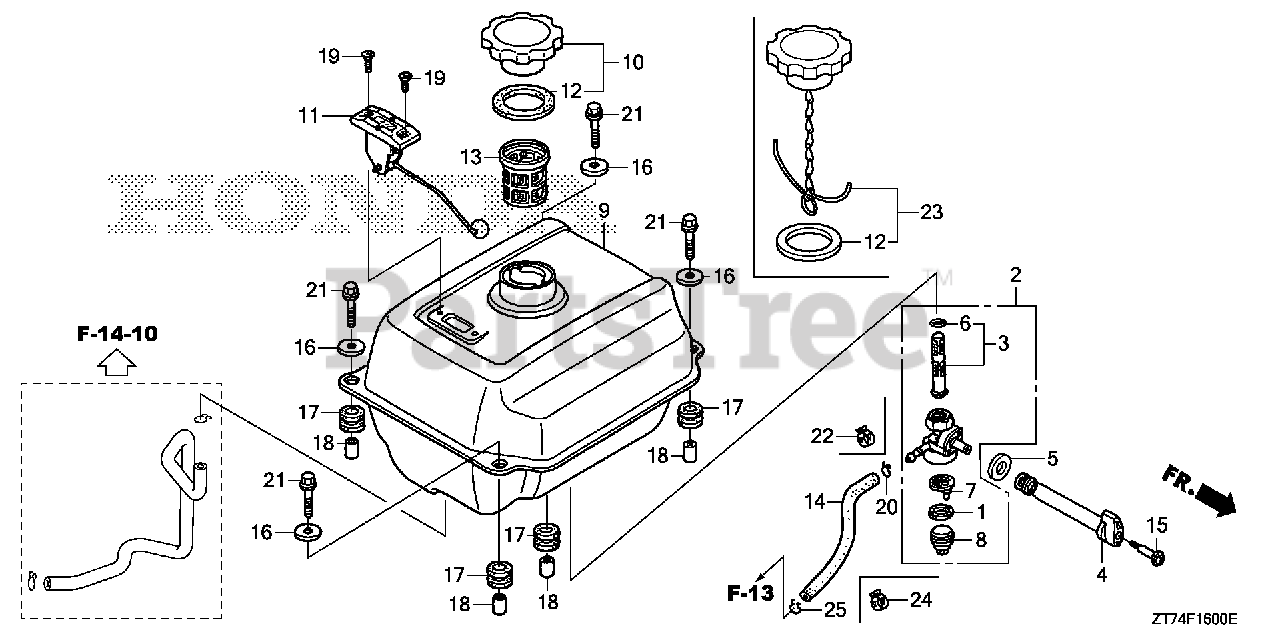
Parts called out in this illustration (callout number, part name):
1	GASKET, FUEL STRAINER CUP
2	PETCOCK ASSY.
3	SCREEN SET, FUEL STRAINER
4	LEVER, PETCOCK
5	SEAL, PETCOCK LEVER
6	O-RING (9.0X1.3)
7	FILTER, CUP
8	CUP, FUEL STRAINER
9	TANK, FUEL *NH1* (BLACK)
10	CAP, FUEL FILLER
11	METER ASSY., FUEL
12	GASKET, FUEL FILLER CAP
13	FILTER, FUEL
14	TUBE, FUEL TANK
15	SCREW, PAN (4X19)
16	WASHER, TANK CUSHION
17	RUBBER, TANK CUSHION
18	COLLAR, TANK CUSHION
19	SCREW, FLAT (5X10)
21	BOLT, FLANGE (6X22)
22	CLAMP, TUBE (D8)
24	CLAMP, TUBE (D8)
